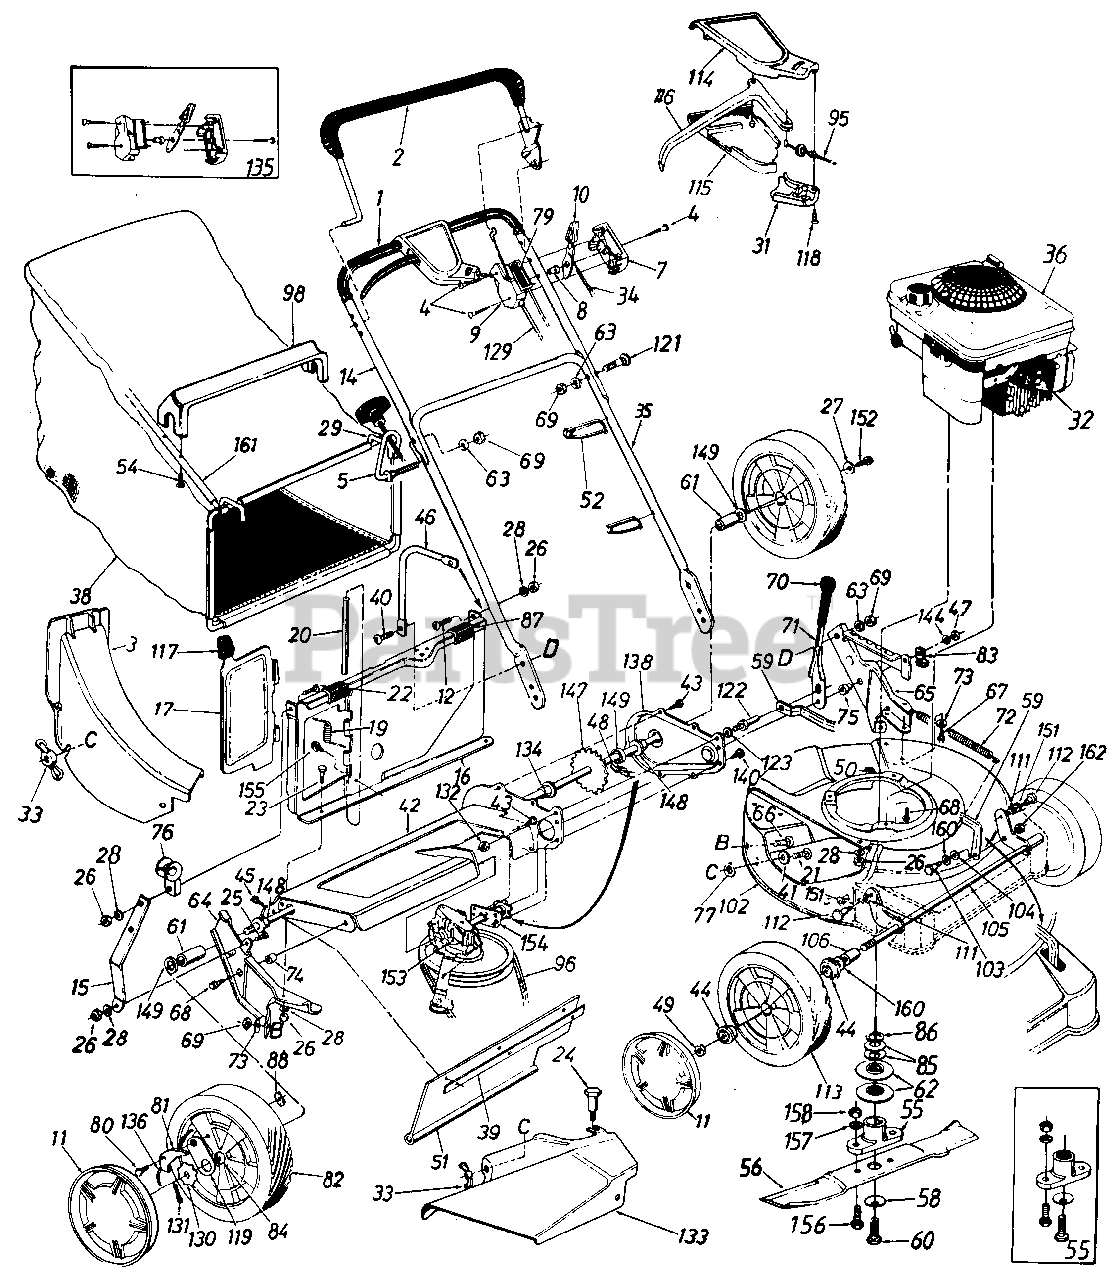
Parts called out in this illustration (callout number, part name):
1	GRIP-FOAM
3	CHUTE ASSY BLACK
4	SCREW-TRUSS MACH
5	SCREW-RECOIL HANDLE GUIDE
7	PANEL HALF-CONTROL
8	PIN-CONTROL DISC
9	PANEL HALF-CLUTCH
10	LEVER-THROTTLE CONT-REV
11	HUB CAP
12	SCREW-TRUSS MACH
14	HANDLE-UPPER
19	SPRING-TORSION
21	BOLT-CARRIAGE 1/4-20 X .62
22	SCREW-TRUSS MACH
23	SCREW-HEX 1/4-20 X .50
24	SCREW-SHLD
25	SCREW-HEX 1/4-20 C .62
26	NUT-HEX 1/4-20
27	WASHER-SPRING BELL
28	LOCK WASHER 1/4 DIA
31	COVER-SP CONTROL
32	INSULATOR-SPARK PLUG
33	NUT-WING
34	WIRE-THROTTLE
35	HANDLE-LOWER PAINTED
38	BAG-GRASS-BLACK
39	STRIP-RETAINING
40	SCREW-TRUSS MACH 5/16-18 X .75
41	WASHER-FL-.344 ID X .62 OD X .033
44	BEARING-BALL
45	SCREW-HEX WASH HD
46	SCREW-HEX WASH HD
47	NUT-HEX LOCK 3/8-24
48	#48 CHAIN 1/2 PITCH
49	NUT-HEX INS L-1/2-20
52	TIE-CABLE
54	SCREW-HEX AB-TAP
55	KIT-BLADE ADAPTER-SPLINED
56	BLADE-21IN
58	BELL-WASH. .46" I.D. X 1.13" O.D.
59	ARM-HGT ADJ CONNECT
60	SCREW-HEX 7/16-20 X 1.50
61	SPACER-.513 ID X .703 OD X .69
62	PULLEY HALF-SERRATED
63	WASHER-LOCK-5/16
64	BRACKET ASSY-HDLE-RH
65	BRACKET ASSY-HDLE-LH
66	BOLT-CARRIAGE 5/16-18 X .62
67	SCREW-HEX WASH HD 5/16-18X1/2
68	SCREW-HEX R
69	NUT-HEX 5/16-18
71	LEVER-HGT ADJ
72	SPRING-EXTENSION
73	WASHER-BELL .337 X .867 X .057
74	SPACER
75	SPACER-SHLD .500 X .100
76	GUIDE-ROPE
77	RETAINER-BOLT 1/4X.50 OD
80	SCREW-SHLD .342 DIA X .268
81	PAWL
82	WHEEL ASSY W/TIRE
85	WASHER-BELL 1.008X 1.625 X .042
86	SPACER-CRANKSHAFT 1.005X1.625X.296
87	CLIP-PANEL BAG
88	NUT-FLAT WELD 1/4 X 20
95	CABLE-CLUTCH
96	BELT-V 3/8 X 31.0
98	HANDLE-BAG-BLACK
102	DECK ASSEMBLY-21IN
103	SCREW-SHLD .500 DIA X .295
104	WASHER-BELL .505 ID X 1.00 OD
105	AXLE ASSY
111	WASHER-INTERN L 3/8 X.56 OD X .018
112	SCREW-SHLD
113	WHEEL ASSY W/TIRE
114	COVER-SP CONTROL
115	COVER-HALF CONT-LWR
116	LEVER-CONTROL
117	KNOB
118	SCREW-FL C-SUNK AB
119	PLATE-PAWL
121	BOLT-CARRIAGE-CURV 5/16-18 X 1.38
122	PIN-SHLD 3/8-24X1.43 LG
123	WASHER-LOCK-3/8
129	CABLE-CONTROL
130	RATCHET
131	PIN-COTTER-1/8 DIA X 1.00
132	NUT-HEX JAM 3/8X24
133	DEFLECTOR-SIDE CHUTE
134	BEARING-HEX FLANGE
135	KIT-THROTTLE CONTROL
136	SPRING-NYLON
144	WASHER-FL-.385 ID X .87 OD X .06
147	SHAFT ASSY-REAR
148	BEARING-HEX FLANGE .506 ID
149	WASHER-FL-.531 X .930 OD X .050
151	BEARING-NYLINER
152	SCREW-1/4-20 X .62
153	TRANSMISSION-COMP
155	SCREW-HEX B-TAP #10 X .38
156	SCREW-HEX 3/8-24 X 1 LG
157	WASHER-LOCK-3/8
158	NUT-HEX 3/8-24
160	WASHER-FL-.510 ID X .75 OD X .033
162	NUT-HEX CENTER L-JAM
16862-0637	PANEL ASSEMBLY-CATCHER(POWDER BLACK) - POWDER BLACK (0637)
16862-0638	PANEL ASSEMBLY-CATCHER(MTD RED) - MTD/TROY-BILT RED (0638)
16862-0648	PANEL ASSEMBLY CATCHER(TECH GRAY) - TECH GRAY (0648)
16862-0662	PANEL ASSEMBLY-CATCHER(OYSTER GRAY) - OYSTER GRAY (0662)
16862-0665	PANEL ASSEMBLY-CATCHER(YARD-MAN GREEN) - YARDMAN GREEN (0665)
17053A-0483	COVER-CHAIN - CHARCOAL GRAY (0483)
17053A-0637	COVER-CHAIN (POWDER BLACK) - POWDER BLACK (0637)
17053A-0638	COVER-CHAIN - MTD/TROY-BILT RED (0638)
17053A-0650	COVER-CHAIN - RED METALLIC (0650)
17053A-0662	COVER-CHAIN - OYSTER GRAY (0662)
17053A-0665	COVER-CHAIN - YARDMAN GREEN (0665)
17053A-0674	COVER-CHAIN - YARDMAN YELLOW (0674)
17055B-0498	AXLE ASSEMBLY-CHAIN (CUB YELLOW) - OLD CUB YELLOW (0498)
17055B-0629	AXLE ASSEMBLY-CHAIN SILVER FLAK - SILVER FLAKE (0629)
17055B-0637	AXLE ASSY-CHAIN - POWDER BLACK (0637)
17055B-0638	AXLE ASSY-CHAIN - MTD/TROY-BILT RED (0638)
17055B-0648	AXLE ASSEMBLY-CHAIN (TECH GRAY) - TECH GRAY (0648)
17055B-0650	AXLE ASSEMBLY-CHAIN RED METALL - RED METALLIC (0650)
17055B-0662	AXLE ASSEMBLY-CHAIN (OYSTER GRAY) - OYSTER GRAY (0662)
17055B-0667	AXLE ASSEMBLY-CHAIN MIDNIGHT BL - MIDNIGHT BLUE (0667)
17055B-0691	AXLE ASSEMBLY-CHAIN (BLACK JACK) - BLACK JACK (0691)
